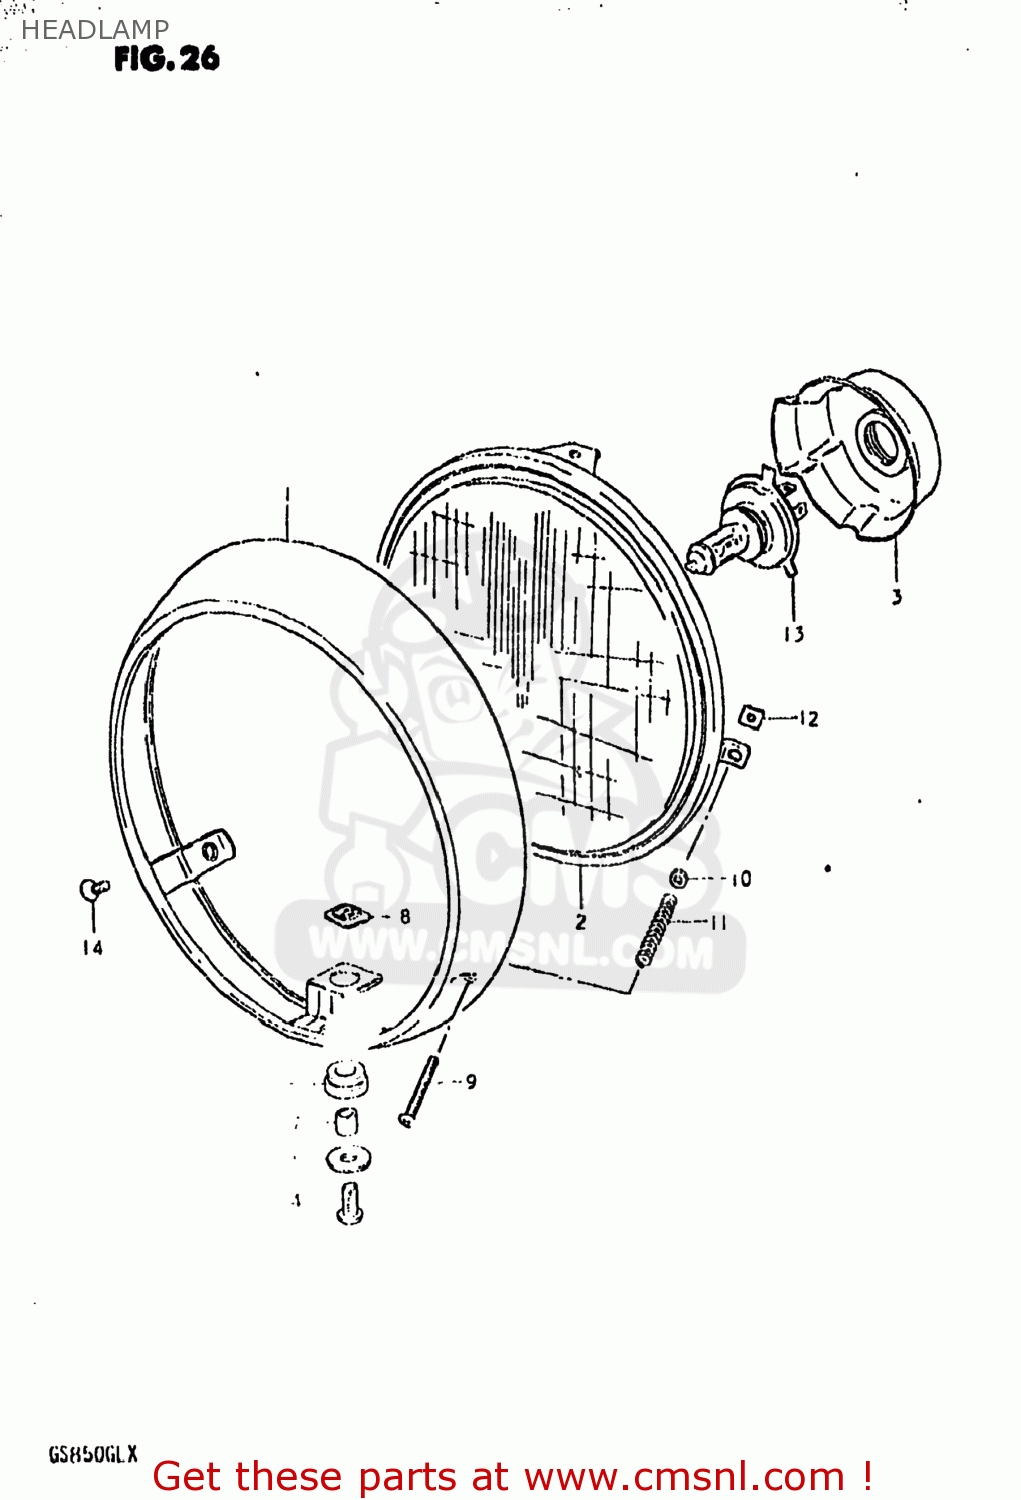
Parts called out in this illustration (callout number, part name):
1	RIM
2	LAMP UNIT
3	COVER,SOCKET
4	SCREW
5	WASHER
6	CUSHION
7	SPACER
8	NUT
9	SCREW
10	WASHER
11	SPRING,HEADLAMP ADJUST
12	NUT,HEADLAMP ADJUSTER
13	BULB(12V60/55W,H4)
14	SCREW
